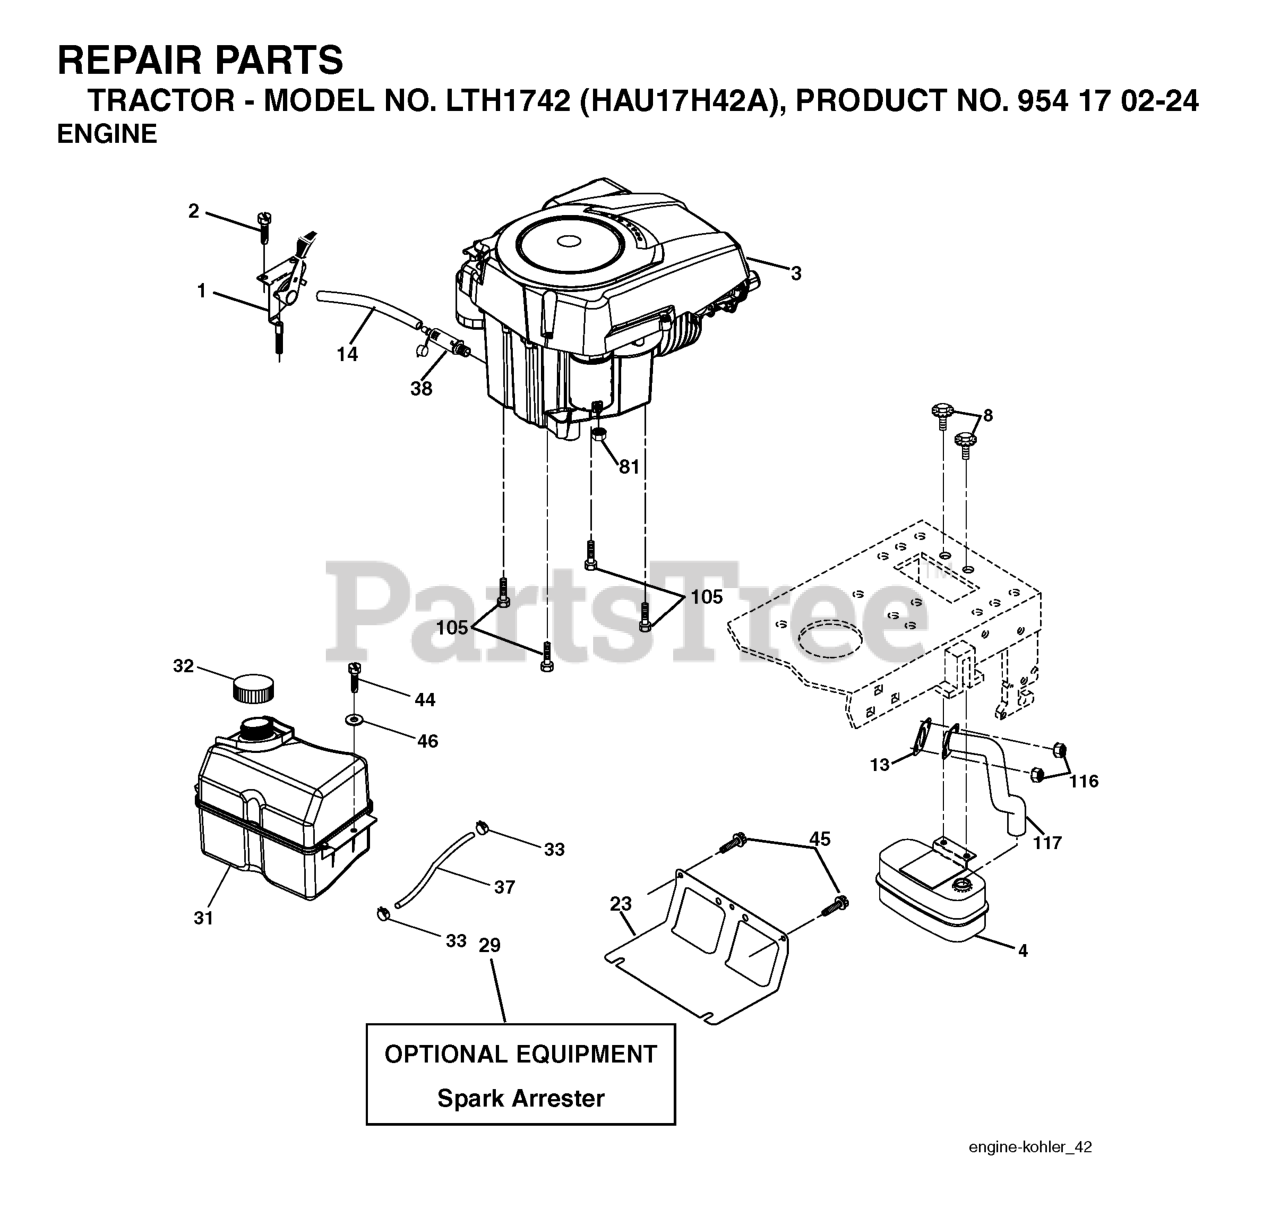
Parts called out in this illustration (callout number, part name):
1	CONTROL.THROTTLE.LT/YT
2	SCREW
4	MUFFLER.SINGLE.CYL.KOHL/B&S
8	BOLT.5/16-18UNCX3/4 W/SEMS.BLK
13	GASKET.EXHAUST.KOHLER
14	TUBE, DRAIN OIL ASM.
23	SHIELD.BROWNING.DBR.GUARD
29	KIT.SPARK ARRESTOR 794945 B&S
31	TANK FUEL
32	FUEL CAP
33	HOSE CLAMP
37	LINE.FUEL.20
38	PLUG DRAIN OIL EASY
44	SCREW HEXWSHR 1/4-20X3/4
45	SCREW, 3/8-16X3/4
81	NUT
105	SCREW 3/8-16X1
116	NUT.HEX.FLANGE.TOPLOCK
117	RP.TUBE.EXHAUST.KOHL.COURAGE
